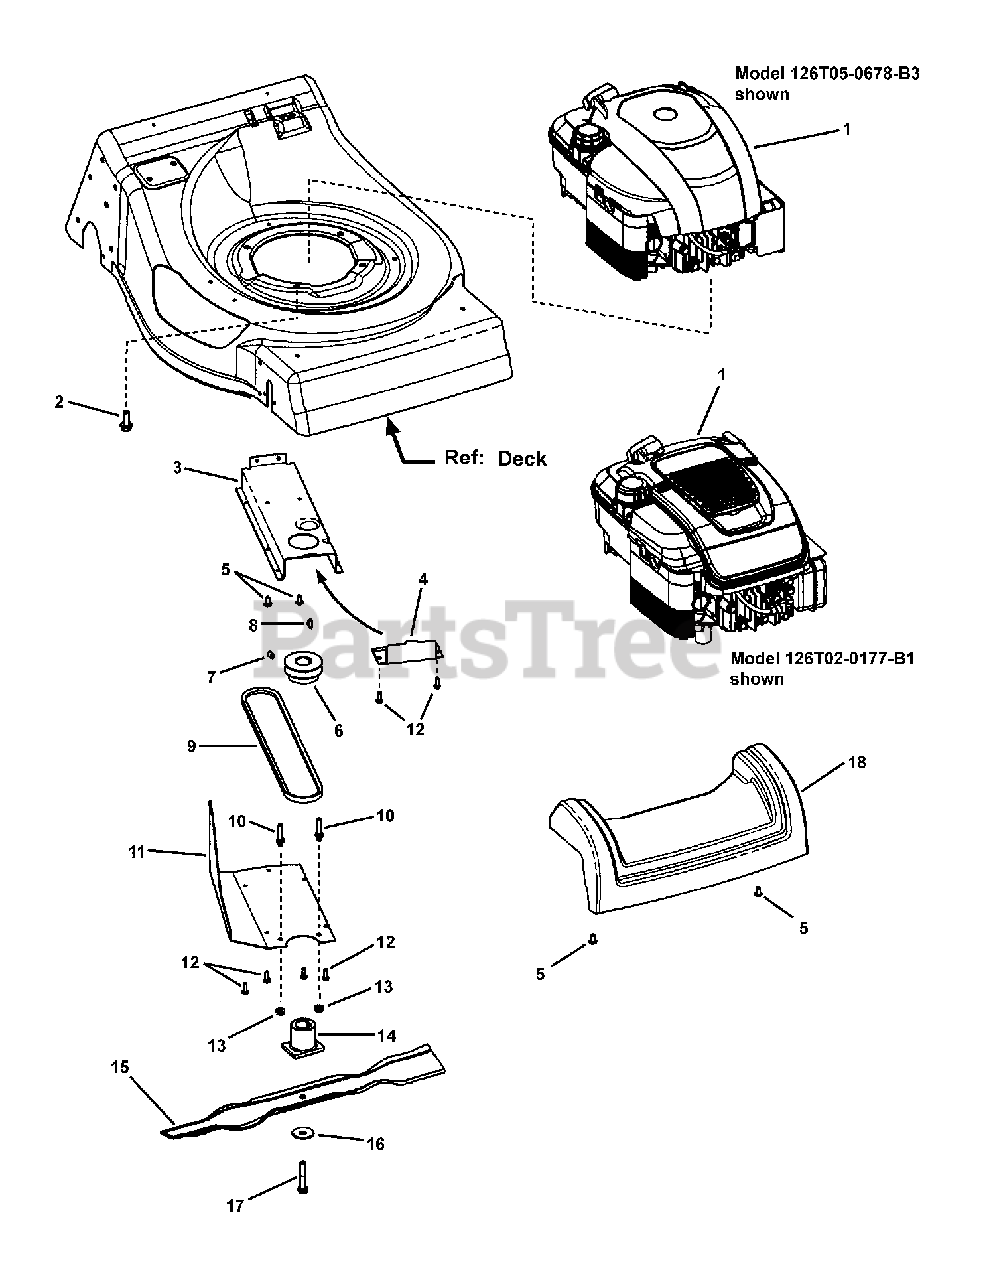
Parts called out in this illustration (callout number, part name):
1	* ENGINE, B&S, X-Spec
1	* ENGINE, B&S, ES
1	* ENGINE, B&S, 675 Ser, ES, X
1	* ENGINE, B&S, 675 Ser, X
1	* ENGINE, B&S, 700 Series, X-Spec
1	* ENGINE, B&S, 700 Series, Quantum E/S (early models)
1	* ENGINE, B&S, 700 Series, Quantum E/S
1	* ENGINE, B&S, 700 Series, X-Spec E/S (early models)
1	* ENGINE, B&S, 700 Series, X-Spec E/S
2	SCREW, 3/8-16 x 1 Hex Washer Self-Tap
3	BELT GUARD
4	COVER, Belt
5	SCREW, 1/4-20 x 1/2 Pan Head Self-Tap, Torx
6	PULLEY, Engine
7	SET SCREW, 5/16-18 x 1/2 Hex Recess
8	KEY, #HP-506 Hi-Pro
9	BELT, 3L, Traction Drive, 21 Pivot Handle
10	BELT GUIDE, Engine, 21 RD
11	COVER, Belt Guard
12	SCREW, #10 x 1/2, AB, w/Washer
13	NUT, 1/4-20 Hex Flange Lock, GR 5, YZ
14	HUB, Blade, 21 WBM, RD, 2 Position
15	BLADE, Wave, 21 Steel Deck
16	WASHER, Cone
17	SCREW, 3/8-24 x 2 Hex Head Cap, GR 5
18	COVER, Front, 21 WBM, RD
